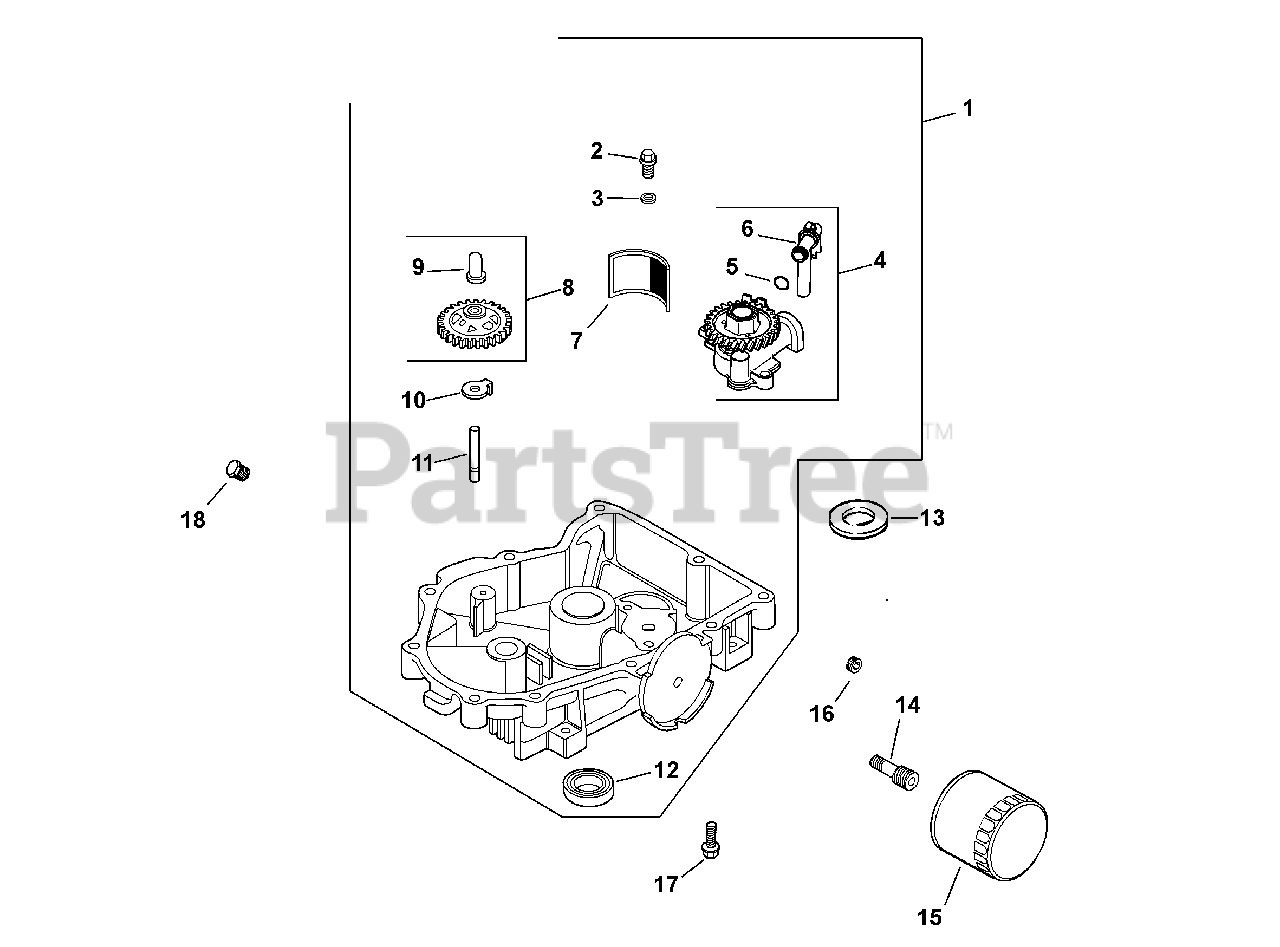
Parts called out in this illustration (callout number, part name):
1	Pan, Oil Assembly (Includes 2-12)
2	Screw, SHD THD FRM M6 x 1.0 x 25
3	Washer, Flat 6MM
4	Kit, Oil Pump Assembly (Includes 5, 6)
5	O-Ring, Oil Pick-Up
6	Tube, Oil Pick Up
8	Kit, Governor Gear w/ Pin (Includes 9)
9	Pin, Governor Regulating
11	Shaft, Governor Gear
14	Nipple, Oil Filter
16	Plug, Pipe CTSK 3/8"
17	Screw, Flg M8 x 1.25 x 45
18	Plug, Hd Pipe 3/8"
